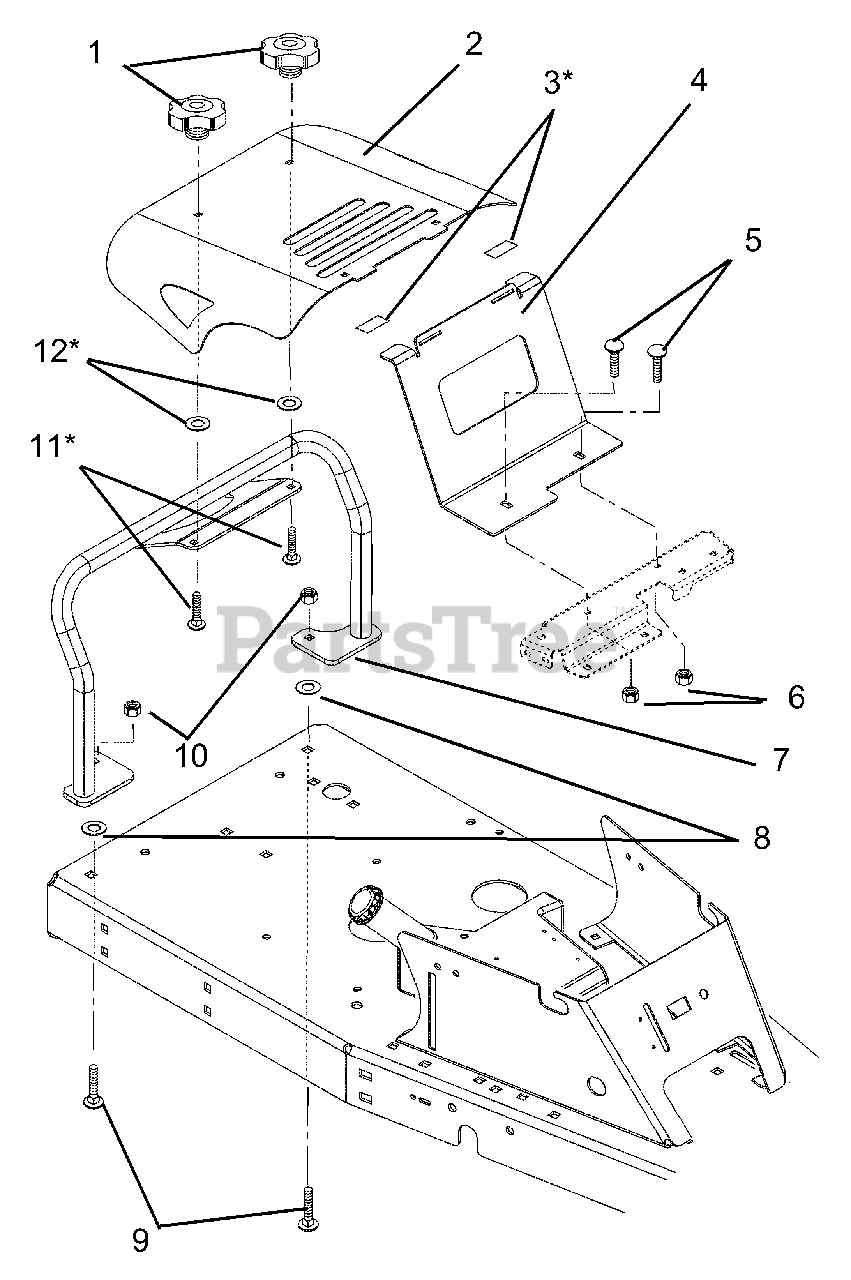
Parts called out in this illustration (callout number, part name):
1	KNOB-CLAMPING, .312-18 NYLOC
2	ENGINE-HOOD ARIENS
2	HOOD ENGINE GRAVELY
3	TAPE-FOAM .12X1.00 VINYL
4	BRACKET-HOOD SUPPORT
5	BLT-RDHDSQNK .31-18X.75 G5BZ
6	@NUT-LK-NYL-FLG .31-18 YWZC
7	WLDM'T TUBE
8	RETAINER, .38 PUSH-ON
9	@BLT-RDHDSHSQNK.38-16X1.0 G5YZ
10	@NUT-LK-NYL-FLG .38-16 YWZC
11	BLT-RDHDSQNK .31-18X1.0 SHTYZ
12	NUT-PUSH .312
